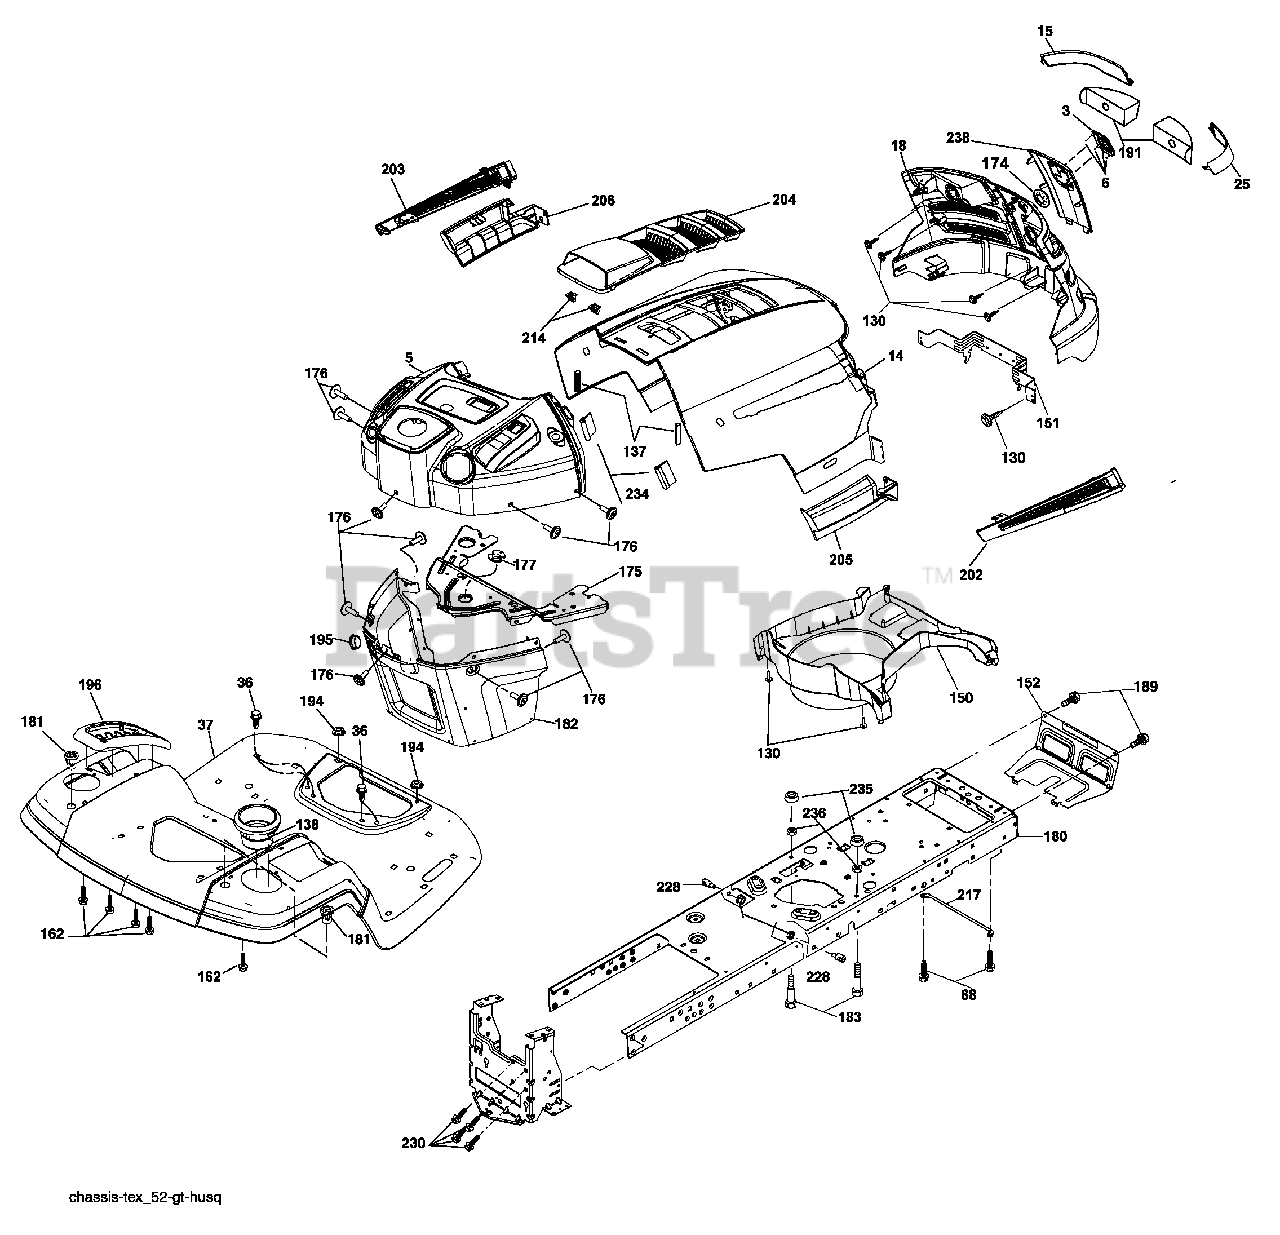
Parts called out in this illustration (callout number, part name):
3	Logo
5	Dash
6	Clip Tinnerman
14	Hood
15	Lens LH
18	Grille/Lens Asm.
25	Lens RH
36	Screw 5/16-18 x 3/4
37	Fender
68	Screw THDROL 5/16-18 x 1/2
130	Screw 10 x 3/4 Single Lead-Hex
137	Bumper Dash
138	Cupholder
151	Bracket Pivot
152	Shield Browning
175	Crossmember
176	Screw 10-24 x 5/8
177	Bushing Steering
180	Chassis
181	Bushing Mtg. Fender Crgo
182	Dash Lower
183	Bolt 5/16-18 Unc x 1-1/4
189	Screw 5/16-18 x 3/4
191	Insert Reflective
194	Nut Lock Hex Flange 5/16-18
195	Plug Dash
196	Console Asm. Deck Lift
202	Vent Side Hood RH
203	Vent Side Hood LH
204	Vent Top Hood
205	Skirt Side RH
206	Skirt Side LH
214	Clip Retainer
217	Rod Pivot Hood
228	Stud Fastener
230	Bolt Shoulder 5/16-18
234	Bumper Hood
235	Spacer Fender
236	Nut Lock 5/16-18 unc
238	Trim
